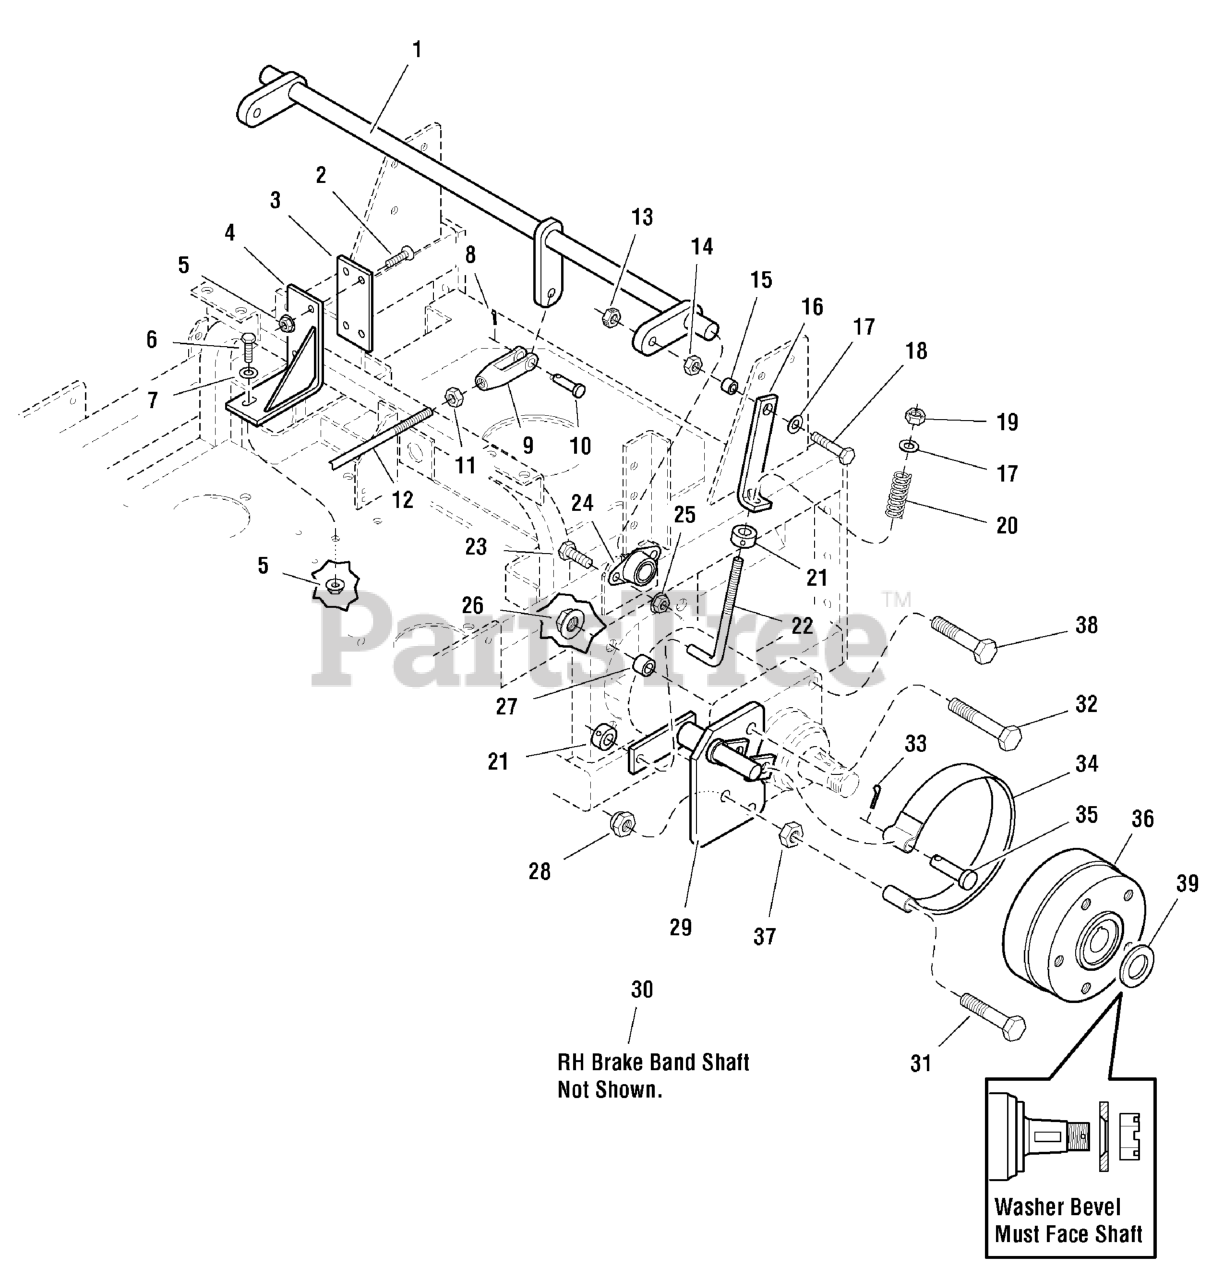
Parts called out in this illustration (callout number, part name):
1	BRAKE CROSS SHAFT
2	SCREW, 5/16-18 X 1 PHILLIPS HD, BZ
3	FRICTION PLATE
4	SUPPORT, Brake Shaft
5	NUT, 5/16-18 HEX SERRATED FLANGE (SMALL)
6	BOLT, 5/16-18 X 1 GD5 YZ
7	WASHER, 5/16" SAE
8	PIN, 3/32 X 0.750, COT, ZINC/CLEAR
9	CLEVIS, 3/8-24, Plastic
10	CLEVIS PIN, 3/8 x 1
11	NUT, 3/8-24 Hex
12	BRAKE CONNECTING ROD
13	NUT, 3/8-16 Hex Side Lock
14	NUT, 3/8-16 Hex
15	SPACER, .38 x .50 x .27
16	LINK, BRAKE LOCK - BLK
17	WASHER, 3/8 SAE
18	BOLT, 3/8-16 X 1-1/2" GD5 CZ
19	NUT, 3/8-16 Hex Top Lock
20	SPRING, Compression
21	COLLAR, 3/8" Set
22	ROD, Brake Adjustment
23	BOLT, 3/8-16 X 3/4" GD5 CZ
24	BEARING, Flange
25	NUT, 3/8-16 Hex Serrated Flange
26	NUT, 1/2-20 Hex Flange Lock
27	SPACER, .51 X .75 X .56
28	NUT, 1/2-13 HEX NYLON LOCK
29	BRAKE BAND SHAFT-LH
31	BOLT, 1/2-13 X 3" GD5 CZ
32	BOLT, 1/2-20 x 3-1/2
33	COTTER PIN, 3/16" x 1-1/4"
34	BRAKE BAND
35	CLEVIS PIN, 1/2 x 2
36	BRAKE HUB
37	NUT, 1/2-13 Hex
38	BOLT, 1/2-20 x 3
39	WASHER, 1 x 2
